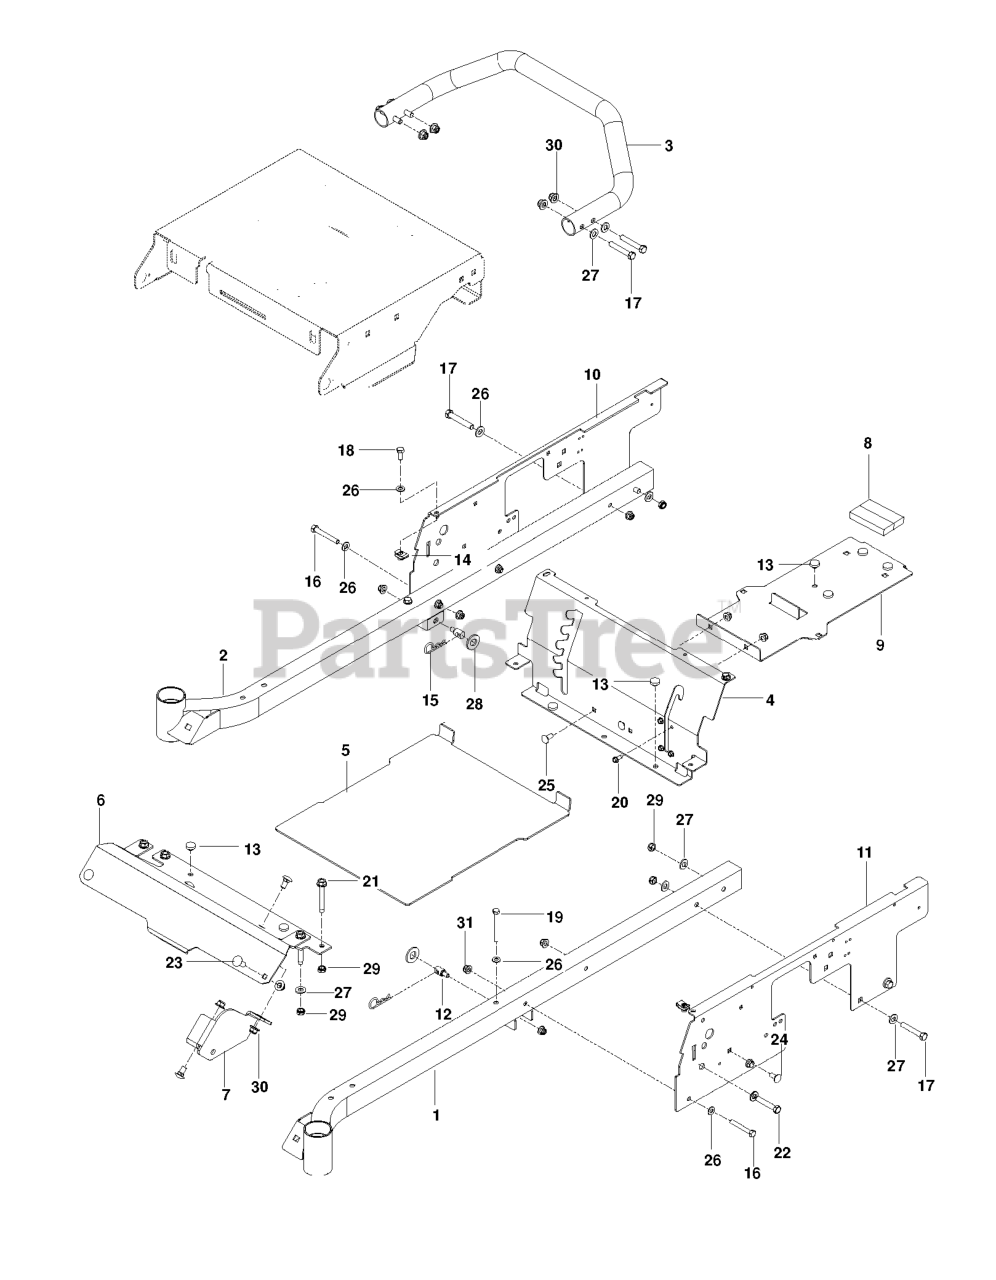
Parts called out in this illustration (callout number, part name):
1	FRAME TUBE, LH, ORG
2	FRAME TUBE, RH, ORG
3	IMPACT BAR, ORG
4	PANEL, SEAT SUPP. ORG
5	PLATE, FOOT W/DECALS, HUSQ
6	FOOT.REST.30/38.ORANGE
7	BRACKET, FRONT DECK, BLK
8	FOAM STRIP, FUEL TANK
9	SUPPORT, TANK/BATT, BLK
10	PLATE.RH.SIDE.ORANGE
11	PLATE.LH.SIDE.ORANGE
12	STUD.FASTNER.W/ANTI-ROTATE
13	GROMMET, BUMPER
14	U-CLIP 5/16-18 NUT RETAINER
15	HAIRPIN #4
17	HCS 3/8C X 2 1/4
18	HCS 5/16C X 3/4
19	HCS 5/16C X 2-3/4
20	SCREW 1/4 X 5/8
21	ENGINE BOLT, SPECIAL
22	HCS 1/2C X 2 3/4
23	RHSNB 3/8C X 1
24	RHSNB 3/8-16 X 3/4 GR5 ZD
25	BOLT 5/16C X 3/4" CARRIAGE
26	FLAT WASHER 5/16 SAE
27	WASHER 3/8 SAE FLAT
28	WASHER 5/8 FLAT
29	NUT HEX 3/8-16 NYLON, THIN
30	NUT 3/8-16 HEX FLG NYLOC ZD
31	5/16-18 NYLOC FLANGE NUT
